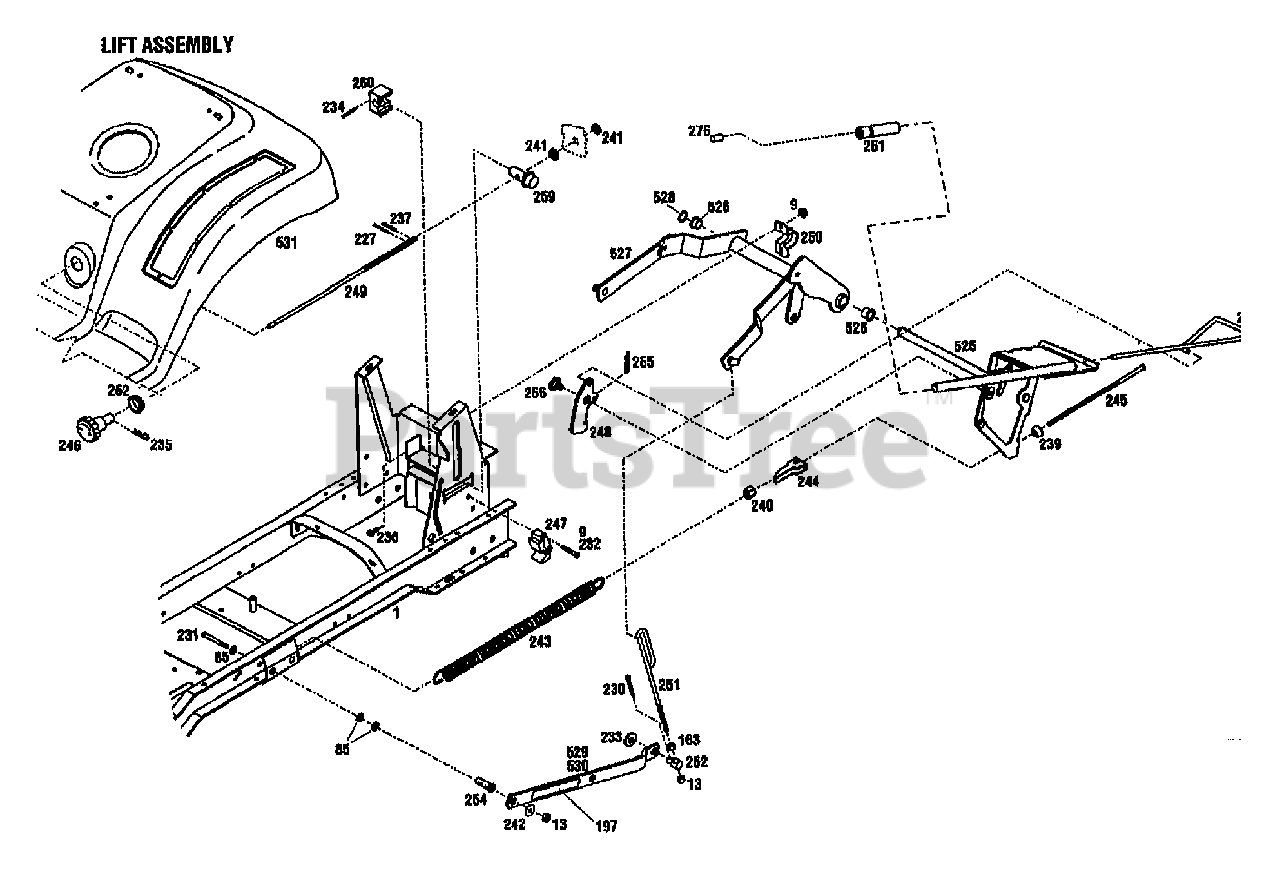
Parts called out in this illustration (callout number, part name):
1	ASSM-FRAME {13078}
1	ASSM-FRAME LTX {13079}
9	NUT-HFLK 5/16-18 ZP
13	NUT-LOCK 3/8-16
85	WASHER-FLAT 3/8 SAE
163	NUT-HEX 3/8-16 ZP
197	DECAL-WARNING
227	PIN-COTTER .125 X .75 ZP
230	PIN-COTTER .120X1.25 ZP
231	SCR-HH 3/8-16X3.0 G5 ZP
232	SCR-HH 5/16-18X1.5 G5 ZP
233	WASHER-1.305X.649X.098 ZP
234	PIN-DRIVE
235	PIN-HITCH
236	SCR-HFLK 5/16-18X.75 ZP
237	PIN-ROLL .156X1.0
239	BEARING-SPHERICAL
240	NUT-SPECIAL 5/16-18
242	WASHER-1.5X.375X.18 ZP
243	SPRING-LIFT ASSIST
244	BRKT-LIFT ASSIST
245	SCR-LIFT ASSIST
246	KNOB-HEIGHT ADJUST
247	BLOCK-DETENT
249	KIT-SVC SCR HGT ADJ
250	CLAMP-LIFT
251	ROD-LIFT {13078}
251	ROD-LIFT {13079}
252	SWIVEL-LIFT REAR
254	SPACER
255	SPRING-EXTENSION
256	SCR-SHOULDER
259	BLOCK-HEIGHT ADJUST
260	COLLAR-HEIGHT ADJUST
261	GRIP-LIFT
262	GROMMET-SNAP BUSHING
276	BUTTON-LIFT
525	HANDLE-LIFT
528	RING-RETAINING EXT .694 ID
529	LINK-LIFT W/DECAL
530	LINK-LIFT W/DECAL
531	FENDER-RED W/DECALS
